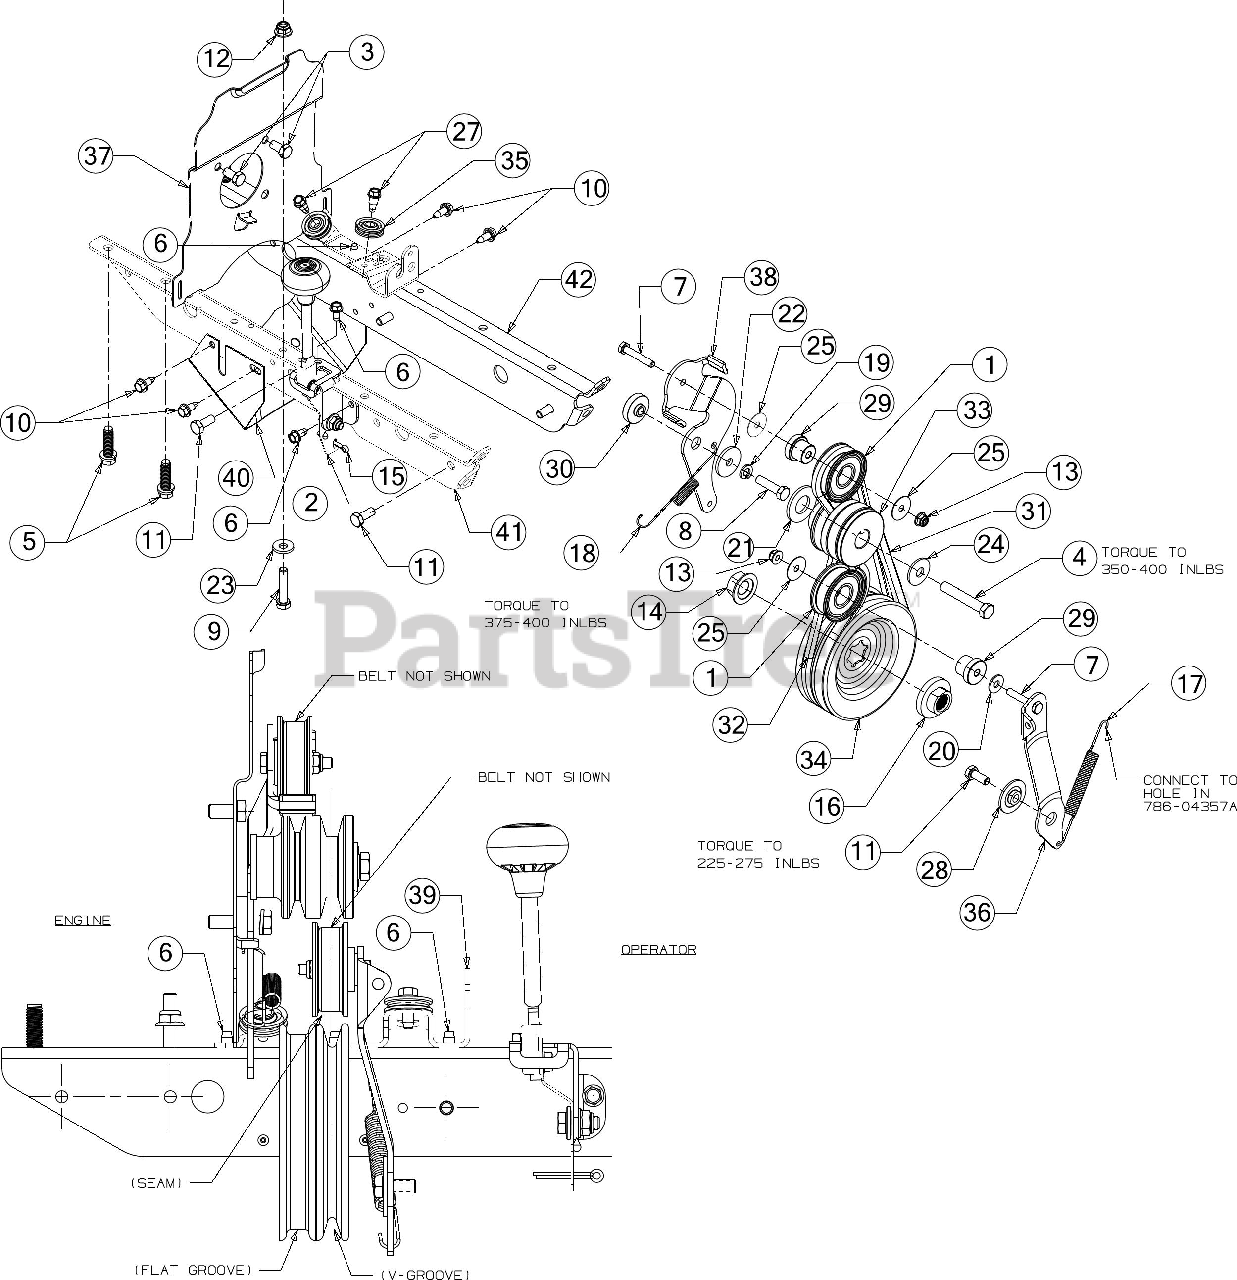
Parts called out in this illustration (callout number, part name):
1	IDLER PULLEY ASSEMBLY
1	BEARING SLEEVE
1	BALL BEARING
2	SHIFT KNOB
2	SCREW 1/4-20 X.500
2	WHEEL DRIVE PIVOT BRACKET
2	SCREW 5/16-18 X .750
2	FLANGE LOCK NUT 5/16-18
2	PIVOT BRACKET SPACER
2	WHEEL DRIVE MOUNT BRACKET
3	HEX SCREW 5/16-24 X .62
4	HEX SCREW 3/8-24 X 2.25 GR5
5	SCREW 3/8-16 X 1.250
6	SCREW 1/4-20 X.500
7	SCREW 1/4-20 X 1.50 GR.5
8	SCREW 5/16-24 X 1.25 GR5
9	SCREW 5/16-18 X 1.5 LG
10	SCREW 1/4-14 X .625
11	SCREW 5/16-18 X .750
12	FLANGE LOCK NUT 5/16-18
13	FLANGE LOCK NUT
14	FLANGE NUT W/HUB
15	COTTER PIN-5/32 DIA
16	PULLEY HUB
17	RETURN SPRING
18	EXTENSION SPRING
19	LOCK WASHER 5/16
20	FLAT WASHER .28 ID X .74 OD X .063
21	FLAT WASHER
22	WASHER-5/16 X 1.25X 1.27
23	BELLVILLE WASHER .827 X .331 X .098
24	BELL WASHER
25	FLAT WASHER
27	SHOULDER SCREW
28	PIVOT IDLER SPACER
29	SHOULDER SPACER
30	PIVOT IDLER SPACER
31	V-BELT FWD DRIVE 4L X 25.375
32	V-BELT REV DRIVE 3L X 29.125
33	ENGINE PULLEY
34	TRANSMISSION PULLEY
35	CABLE GUIDE ROLLER
36	FORWARD IDLER BRACKET
37	REVERSE IDLER BRACKET
38	REVERSE IDLER BRACKET
39	CABLE BRACKET ROLLER
40	PULLEY SHIELD
42	FRAME (RH) 400/460/480/VTT
